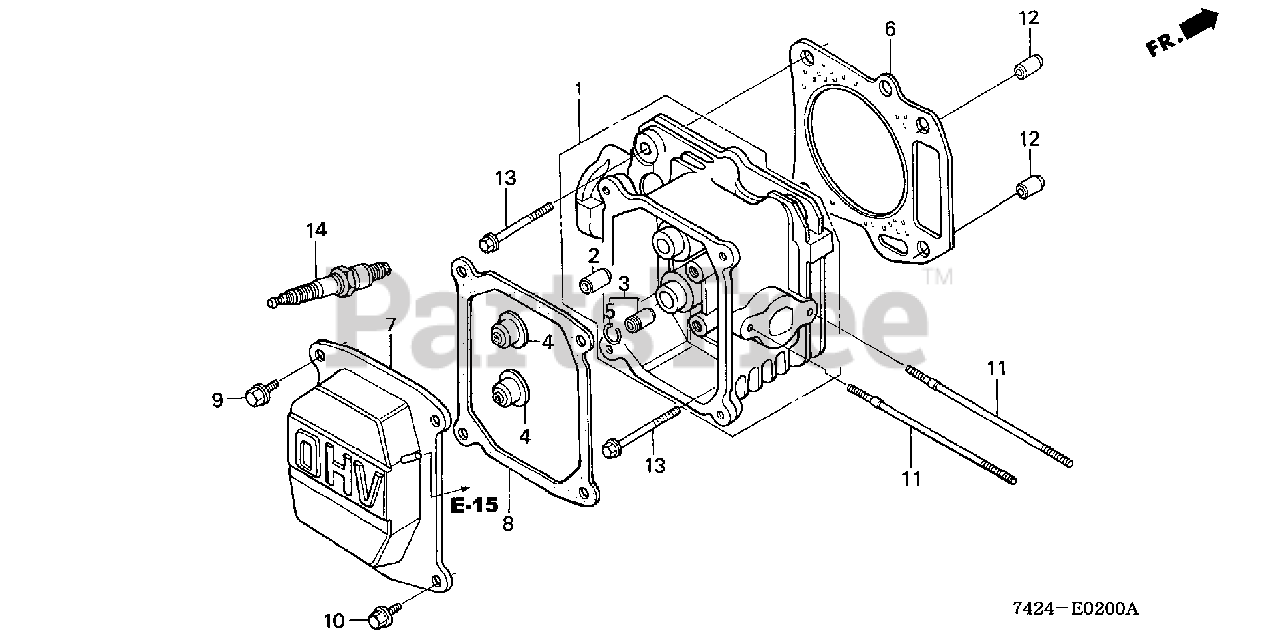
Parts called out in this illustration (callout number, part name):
1	CYLINDER HEAD (USA)
1	CYLINDER HEAD
2	GUIDE, VALVE (OS)
3	GUIDE, EX. VALVE (OS)
4	SEAL, VALVE STEM
5	CLIP, VALVE GUIDE
6	GASKET, CYLINDER HEAD
7	COVER, HEAD
8	GASKET, CYLINDER HEAD COVER
9	BOLT, FLANGE (6X14)
10	BOLT, FLANGE (6X12) (CT200)
10	BOLT, FLANGE (6X13)
11	BOLT, STUD (6X109)
12	PIN A, DOWEL (10X16)
13	BOLT, FLANGE (8X45)
14	SPARK PLUG (BPR4ES) (NGK)
14	SPARK PLUG (W14EPR-U) (DENSO)
